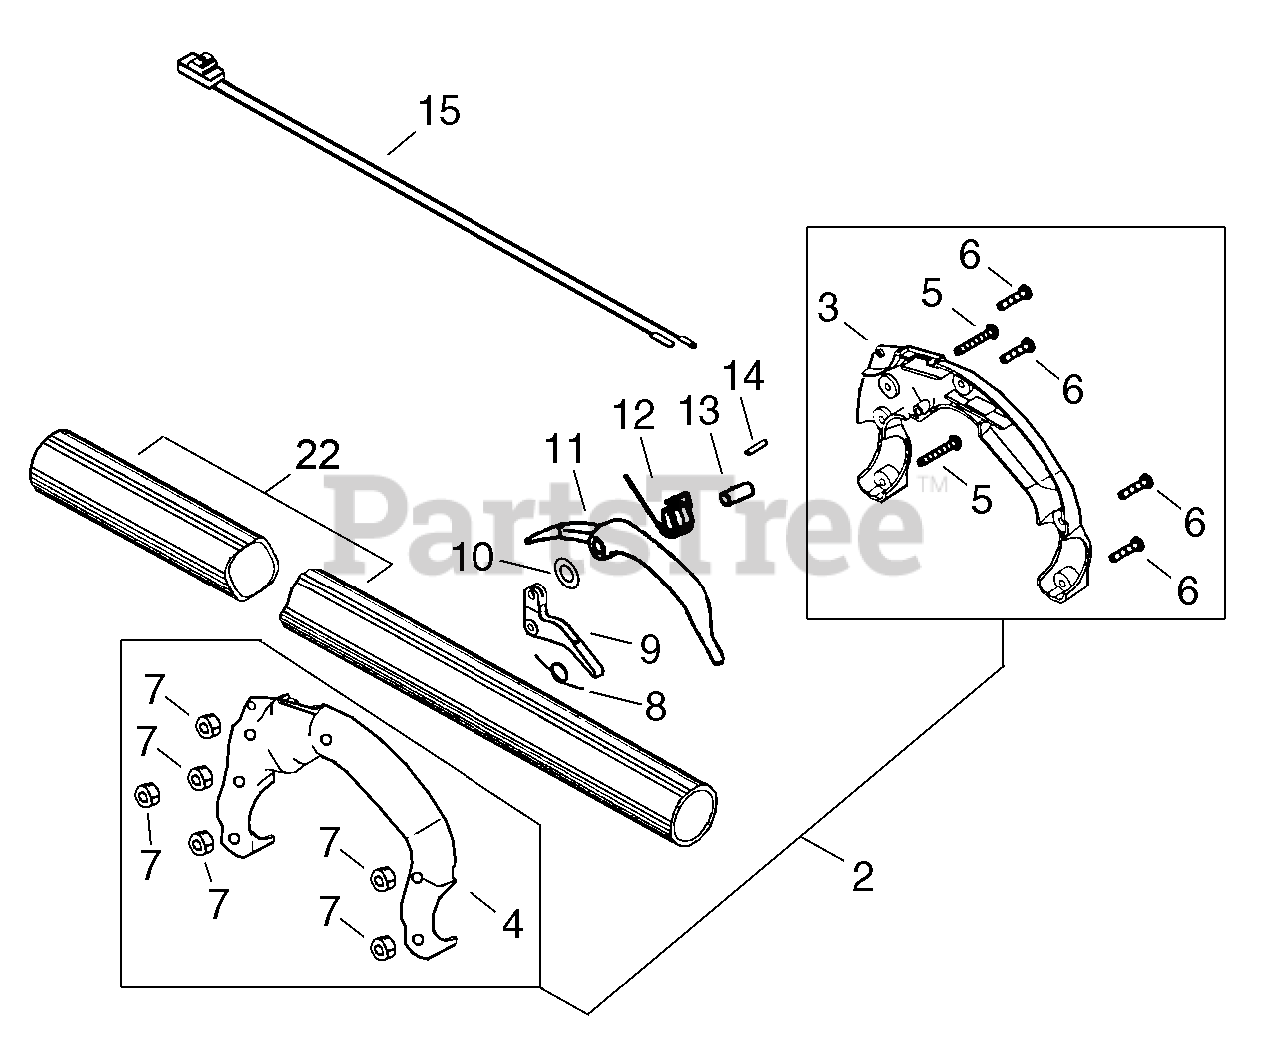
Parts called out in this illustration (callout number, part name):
2	HANDLE ASSY - REAR
3	BODY, RIGHT HANDLE
4	HANDLE, REAR - LEFT
5	SCREW - 10-24 X 1-1/4"
7	LOCKNUT - 10-24
8	SPRING, TRIGGER
9	TRIGGER, THROTTLE
10	WASHER - 5
11	LOCKOUT, THROTTLE
12	SPRING, LOCKOUT LEVER
13	COLLAR - 5.08×14.5
14	PIN - LOCATING
15	IGNITION SWITCH ASSY
22	PIPE, MAIN - ORANGE
